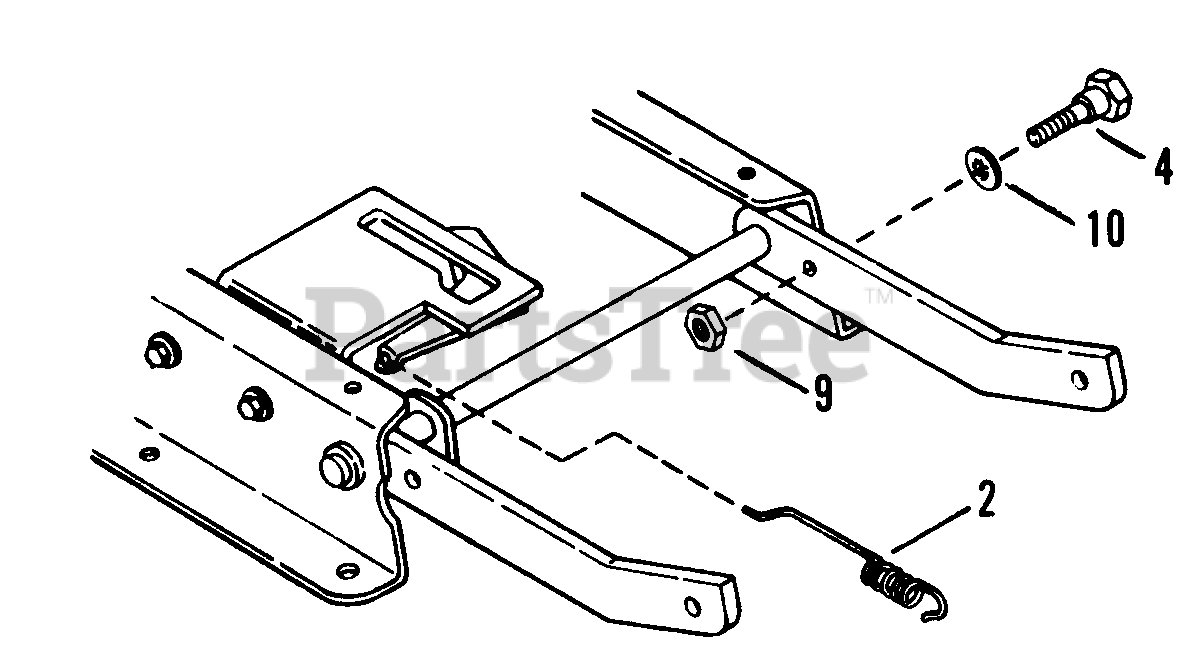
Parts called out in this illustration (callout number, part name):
1	PEDAL, Blade Stop Control
2	SPRING, Latching
3	SPRING, Pedal
4	BOLT, 3/8 - 24 x 3/4" Shoulder
5	BOLT, 3/8 - 24 x 9/16" Shoulder
6	ECCENTRIC, Leveling
7	WASHER, 3/8" Flat
8	WASHER, 1/2 Flat
9	NUT, 3/8 - 24 Hex Lock
10	WASHER, 3/8 Internal Tooth Lock
